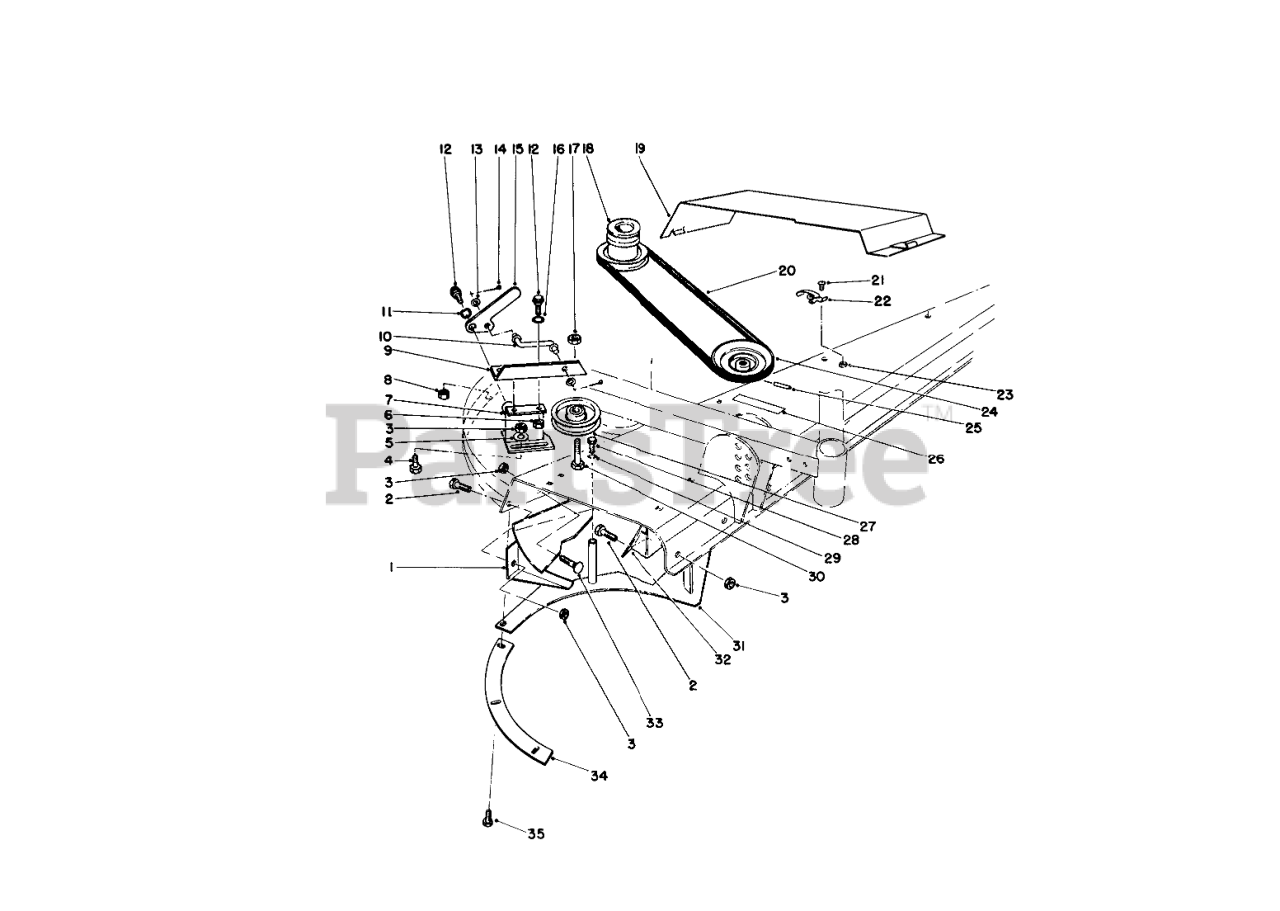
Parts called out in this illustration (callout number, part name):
2	SCREW-HH
3	NUT-LOCK, CONE
4	SCREW-HH
5	WASHER-FLAT
6	NUT-LOCK, NI
8	NUT-LOCK, CONE
11	WASHER-SPRING
12	SCREW-SHOULDER
13	WASHER-PLAIN
14	PIN-COTTER
16	WASHER
17	NUT-LOCK, NI
20	V-BELT
21	SCREW-HWH
22	CLAMP-SLOTTED
23	NUT-LOCK, FLANGE
25	PIN-ROLL, SLOTTED
26	WARNING DECAL
27	PULLEY-IDLER
28	SCREW-HH
29	WASHER-LOCK
30	SCREW-HH
33	BOLT-CARR
35	SCREW-HH
